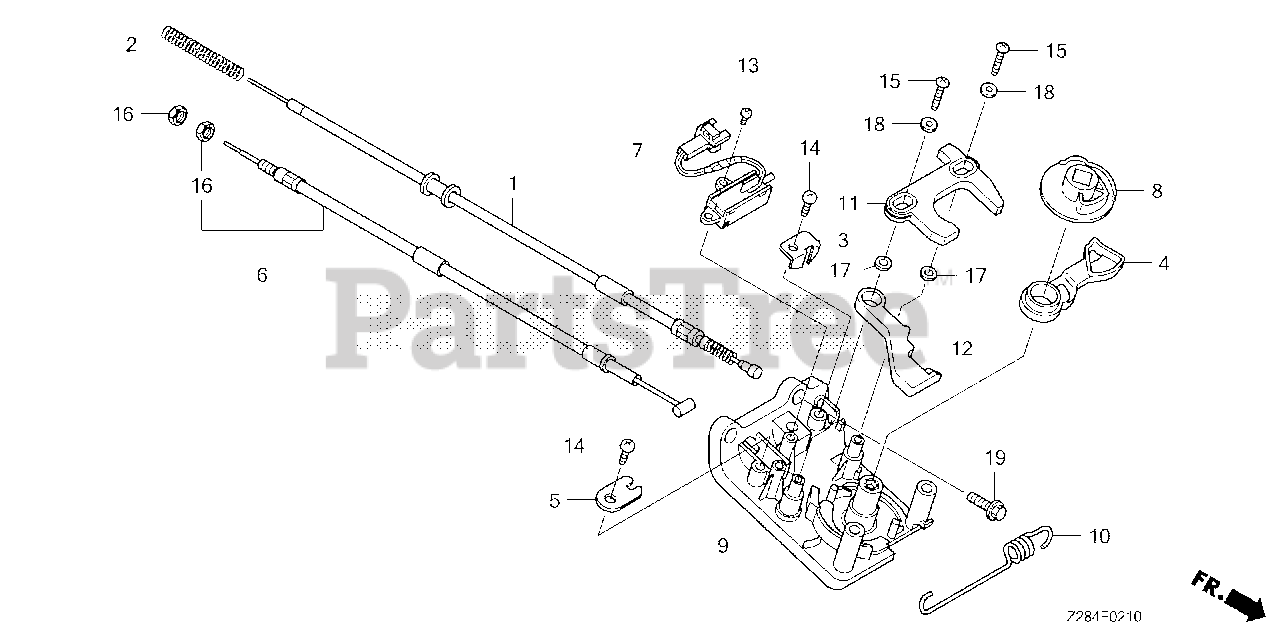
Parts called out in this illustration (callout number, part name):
1	CABLE, CHOKE
2	SPRING, CHOKE
3	BRACKET, CHOKE CABLE
4	ARM, CHOKE
5	BRACKET, PETCOCK CABLE
6	CABLE, PETCOCK
7	SWITCH ASSY., ENGINE STOP
8	CAM, ENGINE SWITCH
9	BASE, ENGINE SWITCH
10	SPRING, SWITCH CAM TENSION
11	PLATE, ENGINE SWITCH
12	PLATE, SWITCH CAM TENSION
13	SCREW, TAPPING (3X10) (NOT AVAILABLE)
14	SCREW, TAPPING (5X16)
15	SCREW, TAPPING (5X25) (P0)
16	NUT, HEX. (6MM)
17	WASHER, PLAIN (8MM)
18	WASHER, PLAIN (5MM)
19	BOLT, FLANGE (6X20)
